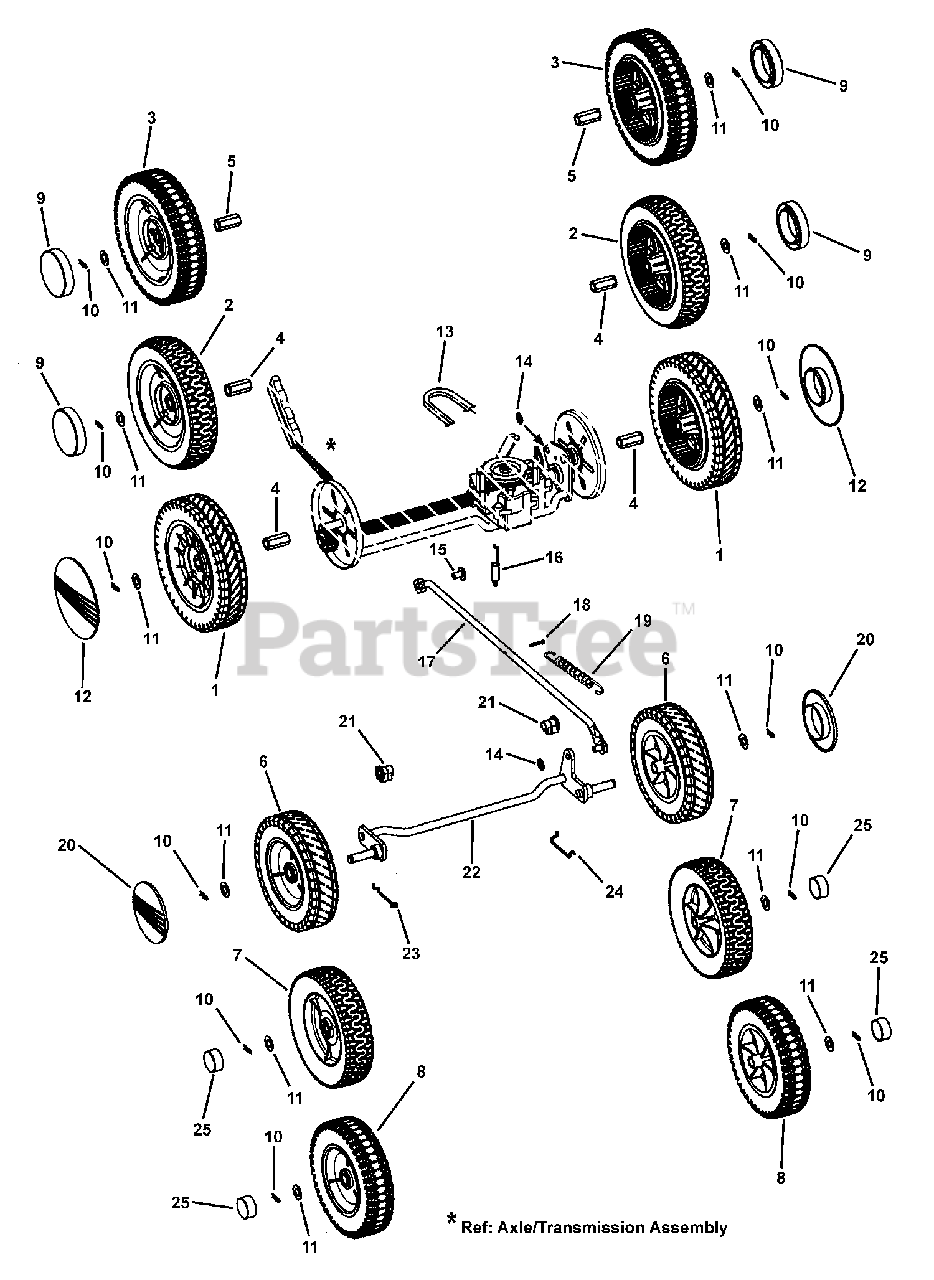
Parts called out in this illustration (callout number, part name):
1	REAR WHEEL ASSY, 9 x 2 ("Mass" Tread)
2	REAR WHEEL ASSY, 9 x 2 (LS Tread)
3	REAR WHEEL ASSY, 9 x 2 (Double Bar II Tread)
4	BUSHING, Wheel (powdered metal)
5	BUSHING, Wheel (nylon)
6	FRONT WHEEL ASSY, 8 x 2 ("Mass" Tread)
7	FRONT WHEEL ASSY, 8 x 2, (LS Tread)
8	FRONT WHEEL ASSY, 8 x 2, (Double Bar II Tread)
9	HUB CAP, 3-1/4" Diameter, Black
10	HAIRPIN, 1/16 x 29/32" Cotter
11	WASHER, 1/2" Flat
12	HUB CAP, 9" Euro
13	BELT, Traction Drive, Sect. 3L, 33.20" effective length
14	WHEEL RETAINER, 3/8"
15	PIN, 3/8 x 5/8"
16	SPRING, Clutch
17	WELDMENT, Tie Bar
18	COTTER PIN, 1/8 x 3/4"
19	SPRING, Tie Bar
20	HUB CAP, Front Wheels
21	BUSHING, Front Axle
22	WELDMENT, Front Axle
23	SPRING, Axle Retaining RH
24	SPRING, Axle Retaining LH
25	HUB CAP, 1-3/8: Diameter
